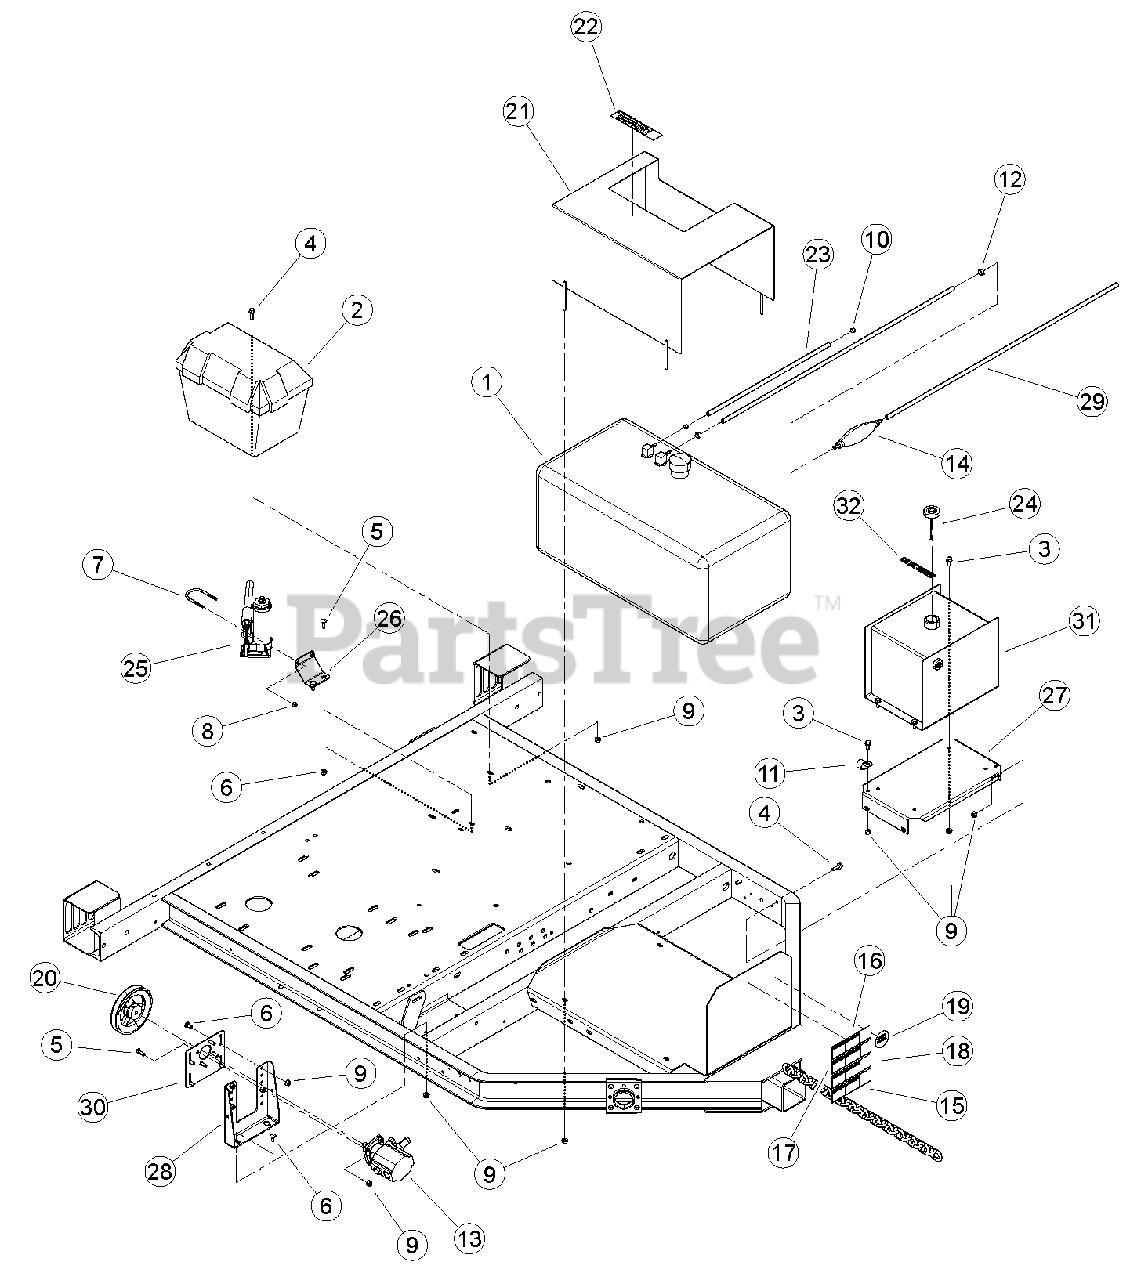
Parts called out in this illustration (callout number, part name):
1	TANK, 19 GAL FUEL
2	BOX, PLASTIC BATTERY
3	BOLT, 5/16 X 3/4 FLANGE NC
4	BOLT, 5/16 X 1 FLANGE NC
5	BOLT, 5/16" X 1" GR5 CRG ZP
6	BOLT, 5/16 X 3/4 GR5 CRG NC ZP
7	U-BOLT, 1/4 X 1-1/2 PIPE
8	NUT, 1/4-20 NYLOCK-FLANGE
9	NUT, 5/16-18 NYLOCK-FLANGE
10	CLAMP, 15/32 SPRING
11	CLAMP, 1" COATED METAL
12	CLAMP, 9/16 SPRING
13	PUMP, 2 STAGE CW HI/LO 0.605 DISP.
14	PUMP, HAND PRIMER
15	DECAL, SAFETY CHAINS
16	DECAL, TRAILER ELECTRICAL
17	DECAL, CHECK WHEELS
18	DECAL, SAFE COUPLING
19	DECAL, NATM COMPLIANCE
20	PULLEY, 5.6 - 1/2" BORE FHP B
21	ASSEMBLY, FUEL TANK CLAMP W/ DECALS
22	DECAL, DIESEL FUEL
23	HOSE, 76" FUEL RETURN
24	CAP, HYDRAULIC W/ DIPSTICK
25	JACK, HYDRAULIC 2 TON
26	PLATE, JACK MOUNT
27	SHEET, TANK MOUNT
28	BRACKET, MOUNT HYDRAULIC PUMP
29	HOSE, 38" FUEL
30	PLATE, PUMP MOUNT
31	ASSEMBLY, HYDRAULIC TANK 3.25 GAL
32	DECAL, HYDRAULIC FLUID
